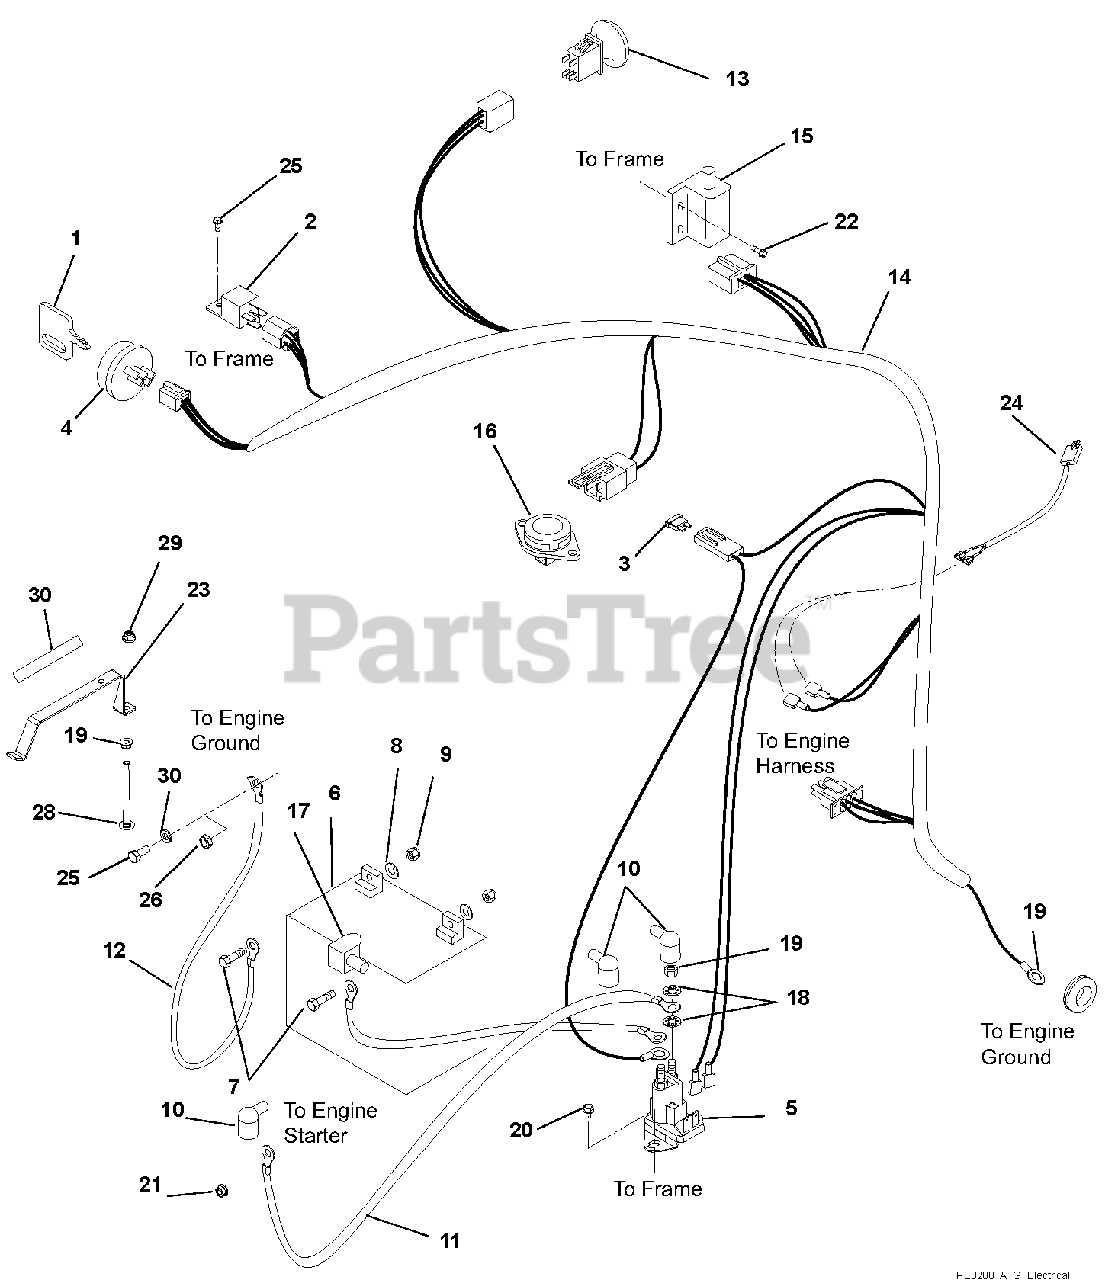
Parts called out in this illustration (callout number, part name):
2	Relay
3	Fuse, 30 AMP
4	KEYSWITCH-IGNITION 3 POS
5	Solenoid
6	Battery, 12V 20 Hour (Can be replaced with U1 190 or larger)
7	Bolt, Hex .25-20 x .75
8	Washer, Flat Steel .281 x .62 x .065
9	Nut, KEPS .250-20
10	Boot, Eyelet Terminal
11	Cable, POS
12	Ground Cable
13	Switch, Clutch With Retainer
14	Harness, Wiring ZT
15	Switch, Double Pole N.O. / N.O.
16	Switch, Snap Mounting (N.O.)
17	Insulator
18	Washer, Locking .31
19	Nut, Jam .31-24
20	Screw, Tapping .250-20 x .37 Hex Washer Head
21	Nut, Locking Top Flange .25-20
22	Screw, 12-14 x .75 HX
23	Hold Down, Battery
24	Harness, Clutch
25	Screw, Tapping 12-24 x .50 Hex Washer Head
26	Nut, Locking Center Jam .375-16 (915146, 168)
27	Wire Clip (915148, 150, 170)
28	Bold, Round Head Square Neck .25-20 x 4.50
29	Nut, Locking Nylon Flange .25-20
30	Decal, U1 Battery Replacement
